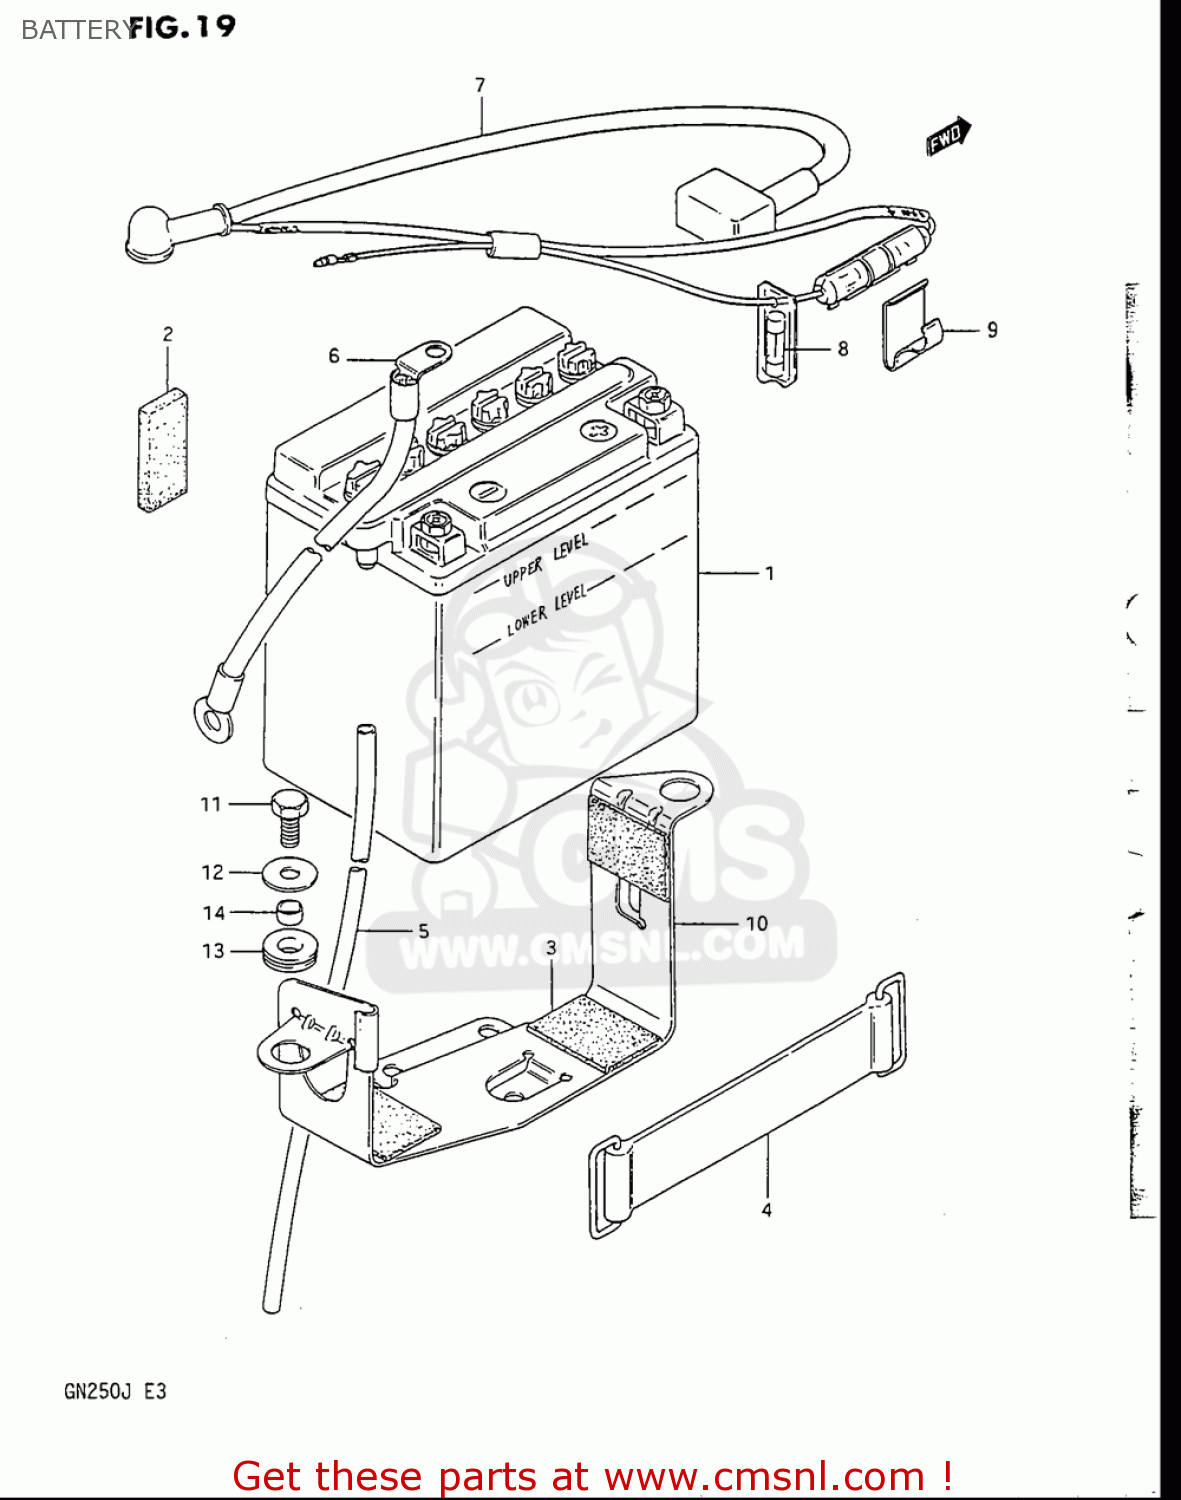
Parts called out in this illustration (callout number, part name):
1	BATTERY ASSY (12V)
2	PROTECTOR(170X95X3.0)
4	BAND
5	HOSE,BATTERY EXHAUST(L:780)
6	LEAD WIRE,BATTERY(-)
7	CASE ASSEMBLY,FUSE (WITH
8	FUSE(15A)
9	HOLDER,FUSE CASE
10	HOLDER,BATTERY
11	BOLT
12	WASHER(6.5X20X1.2)
13	CUSHION
14	SPACER(6.1X9X7.5)
